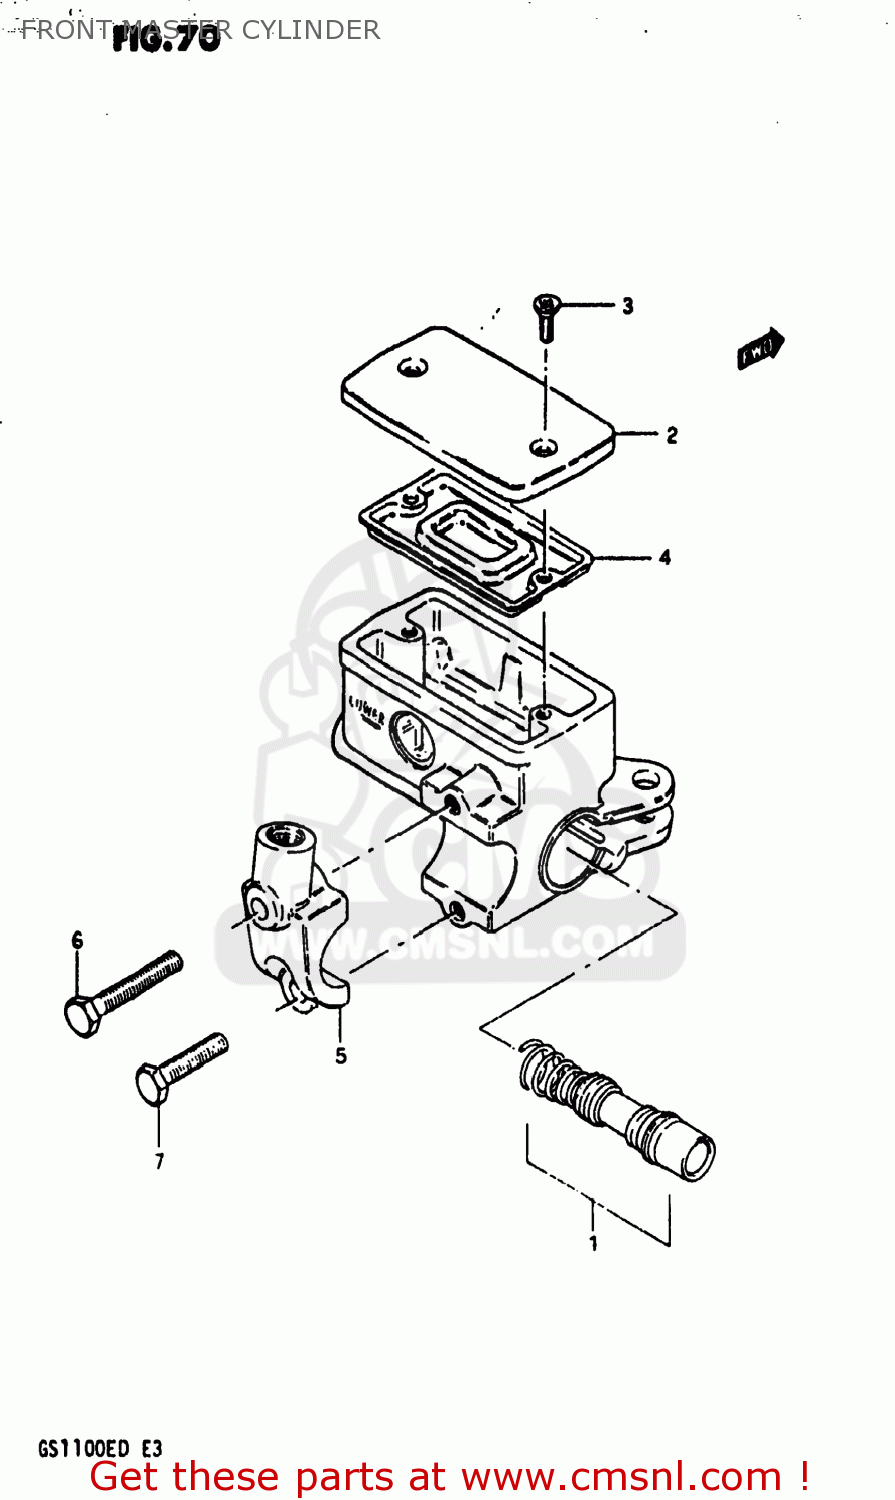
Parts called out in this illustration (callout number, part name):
1	PISTON & CUP SET
2	CAP,MASTER CYLINDER,REAR
3	SCREW,RESERVOIR CAP
4	DIAPHRAGM,MASTER CYLINDER
5	HOLDER
6	BOLT,MASTER CYLINDER H
7	BOLT,MASTER CYLINDER H
